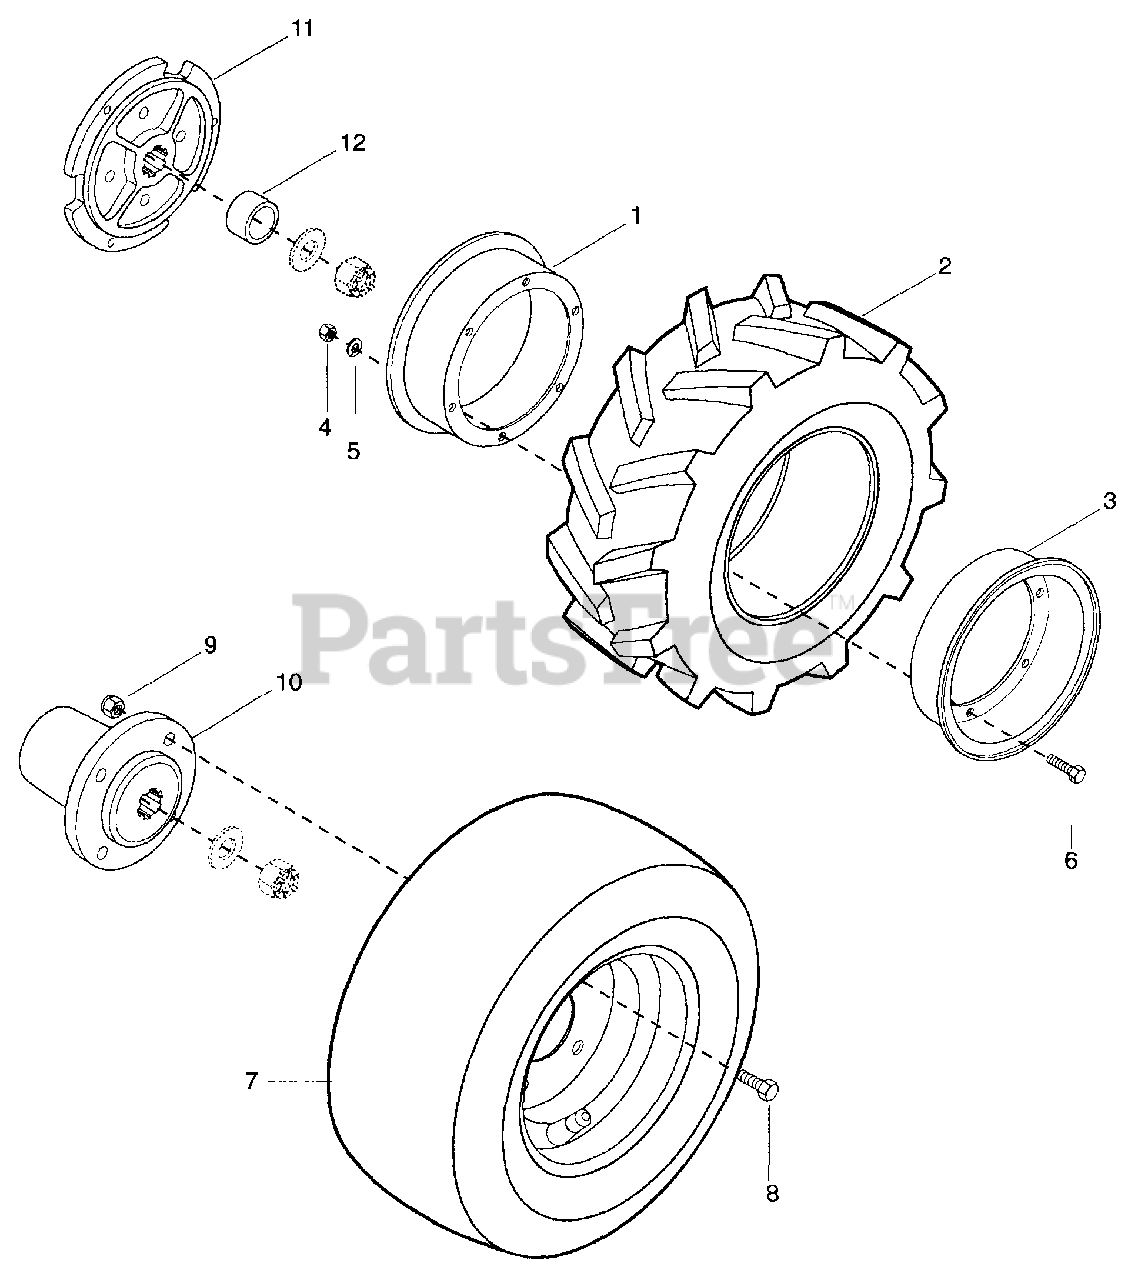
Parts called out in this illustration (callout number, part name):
1	Wheel 7.71 x 1.25
2	Tire 16 x 5W x 3 Firestone
3	Wheel-Disc 6.75 x 9.219
4	Nut-Jam .375-16
5	Washer-Lock .375 x .094
6	Bolt-Hex .38-16 x .625
6	Bolt-Hex .38-16 x 1.00 Grade 5
7	Tire/Wheel Assembly 8.50-8 x 18
7	Tire/Wheel Assembly 16 x 6.50-8
7	Tire/Wheel Assembly 4.80/4.00-8 Stud
7	Tire/Wheel 4.80/4.00-8 Trac Right Hand
7	Tire/Wheel 4.80/4.00-8 Trac Left Hand
8	Bolt-Hex .50-13 x 1.625
9	Nut-Locking-Nylon .50-13
10	Hub, 7" Wheel
11	Hub, Wheel
12	Bushing, Sleeve 1.02 x 1.37 x 1.13
